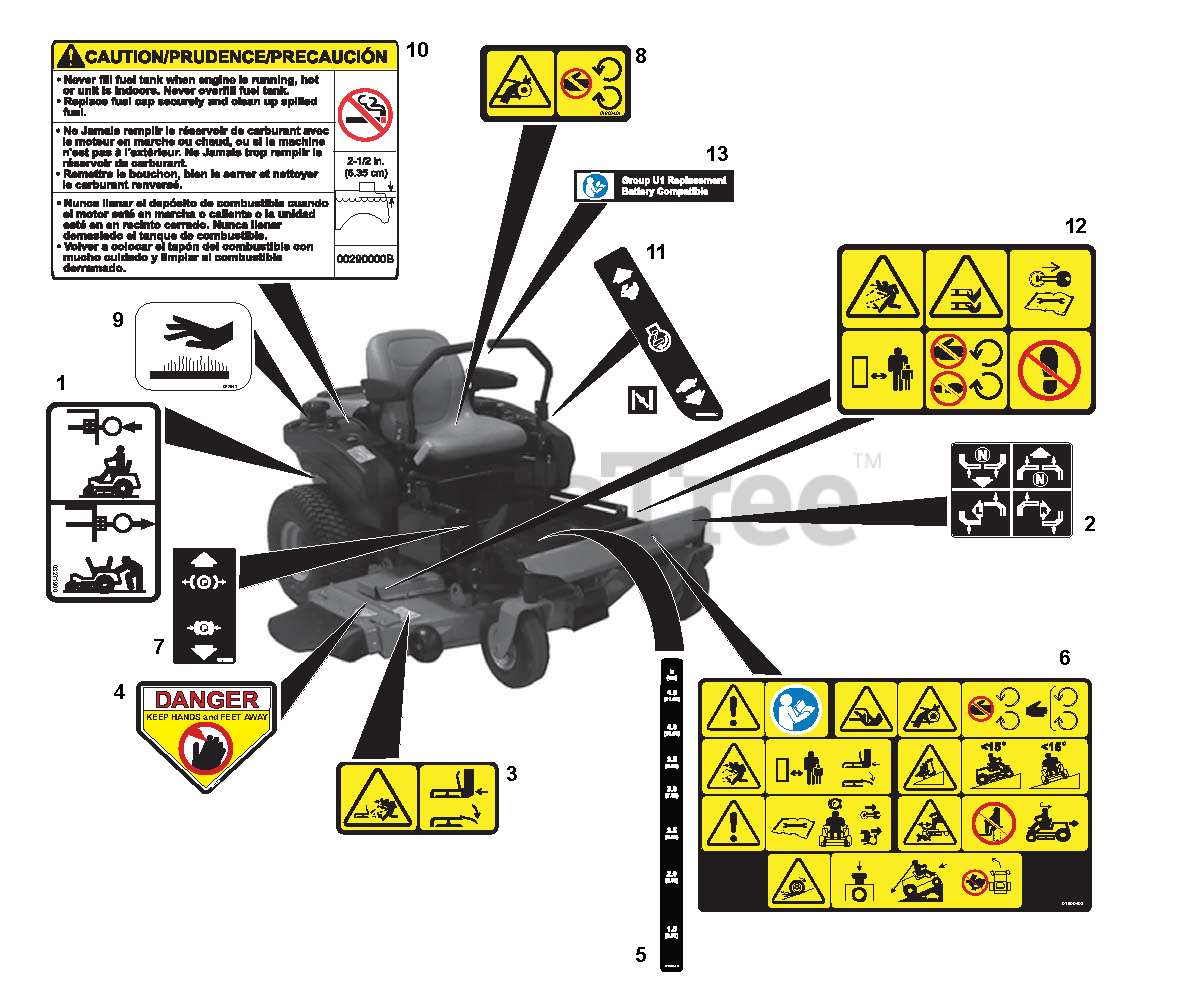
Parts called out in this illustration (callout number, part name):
1	DECAL, TRANSMISSION DISCONNECT
2	DECAL, INSTRUCTIONAL-STEERING
3	DECAL, SAFETY - DECK GUARDING
4	DECAL, DANGER
5	DECAL, CUT HEIGHT XL
6	DECAL, MAIN SAFETY
7	DECAL, PARKING BRAKE LEVER
8	DECAL, SAFETY - GUARDING
9	DECAL, HOT SURFACE
10	DECAL,FUEL WARNING
11	DECAL, SPEED CONTROL
12	DECAL, SAFETY - MOWER DECK
13	DECAL, U1 BATTERY REPLACEMENT
